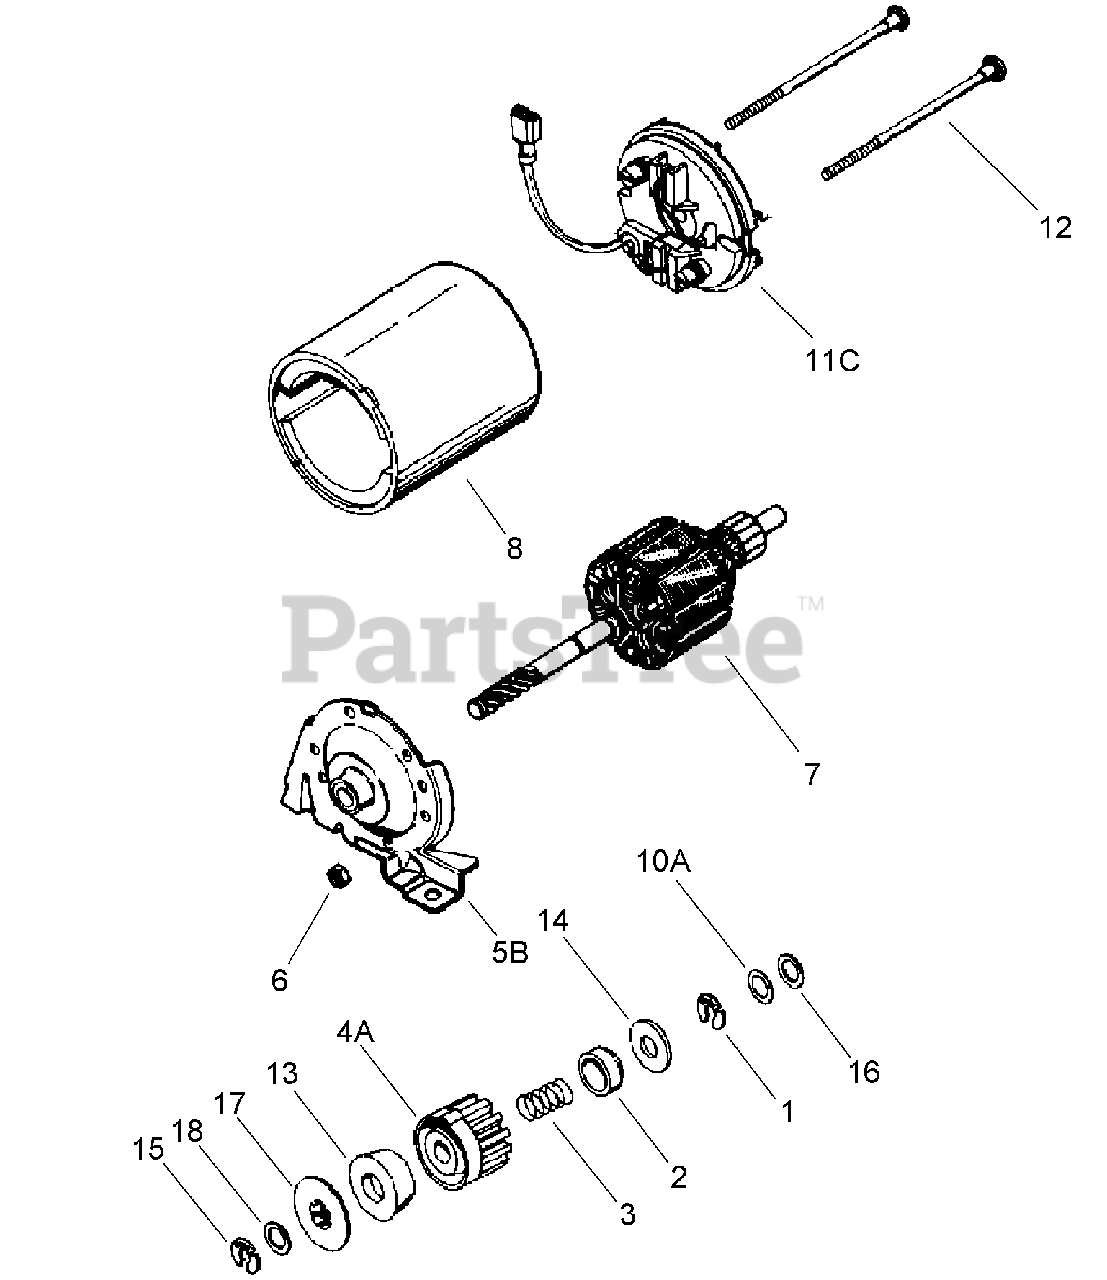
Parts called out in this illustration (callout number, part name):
1	Ring-Retaining
2	Retainer-Spring
3	Spring
4A	Gear
5B	Drive End Cap ASM
6	Nut-Lock
7	Armature
8	Housing ASM
10A	Washer-Thrust
11C	Commutator End Cap ASM (Includes brushes)
12	Bolt
13	Driver-Pinion
14	Washer-Cup
15	Ring-Retaining
16	Washer
17	Nut-Drive
18	Washer
